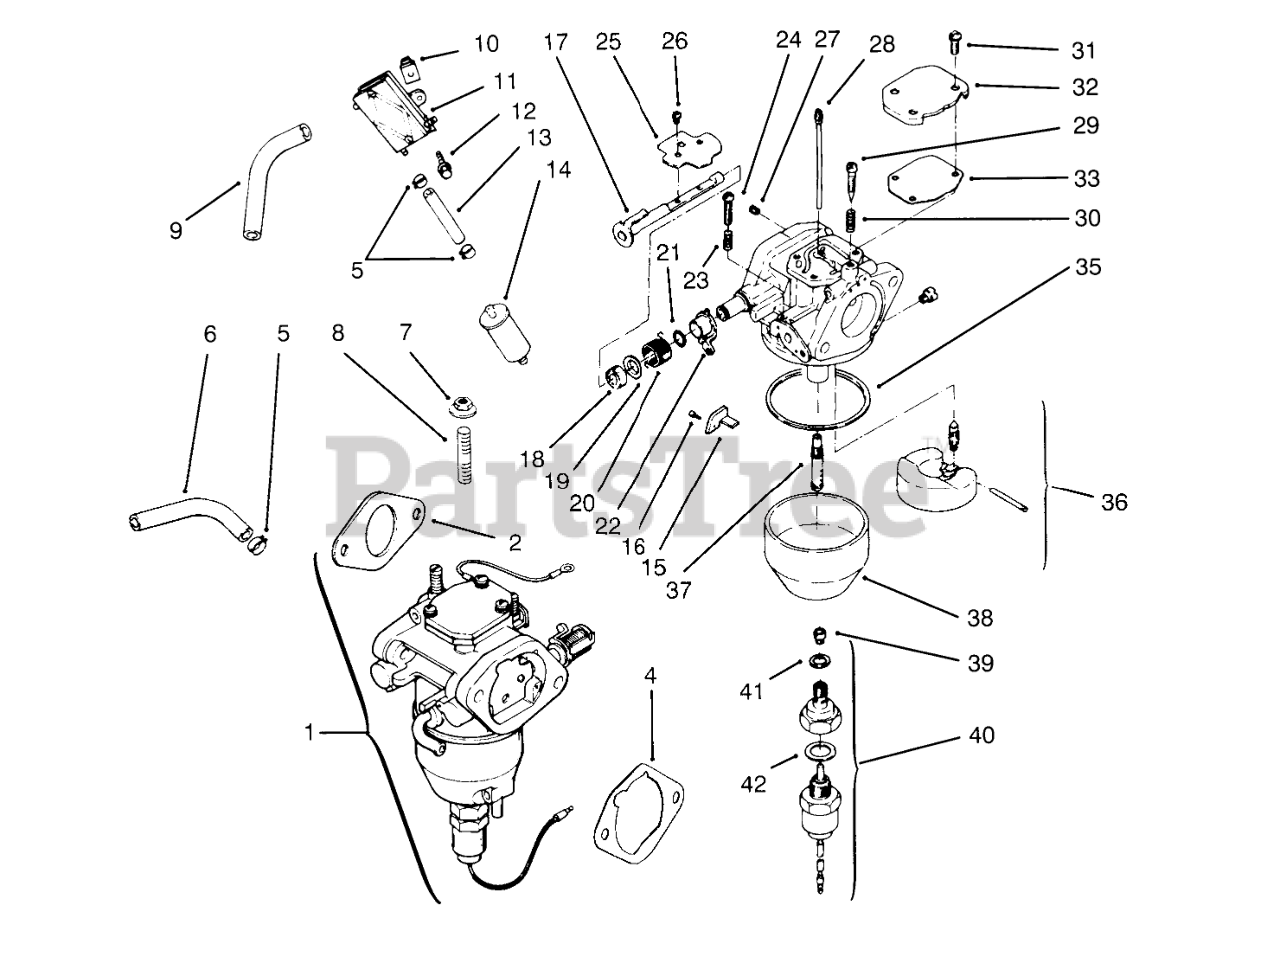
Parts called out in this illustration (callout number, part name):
1	Kit-Carb INCL 2/4/15-42 (Only On: 72103)
2	Gasket-Carburetor (Only On: 72103)
4	Gasket-A/C Base (Only On: 72103)
5	Clamp-Hose (Only On: 72103)
6	Line-Fuel 10 1 /2" (Only On: 72103)
7	Nut M6x1.0 (Only On: 72103)
8	Stud M6x1.0x95 (Only On: 72103)
9	Line-Fuel 12" (Only On: 72103)
10	Nut-Plastic (Only On: 72103)
11	Pump-Fuel (Only On: 72103)
12	Screw-Cable Clip (Only On: 72103)
13	Line-Fuel 3 1/2" (Only On: 72103)
14	Filter-Fuel (Only On: 72103)
15	Bracket-Throttle Stop (Only On: 72103)
16	Screw M2.5X45X5.5 (Only On: 72103)
17	Shaft-Choke (Only On: 72103)
18	Washer (Only On: 72103)
19	Collar-Choke (Only On: 72103)
20	Spring-Choke Return (Only On: 72103)
21	Ring-Choke Lever (Only On: 72103)
22	Lever-Choke (Only On: 72103)
23	Spring-Throttle Screw (Only On: 72103)
24	Screw-Throttle Adjust (Only On: 72103)
25	Valve-Choke (Only On: 72103)
26	Screw-Throttle Shaft (Only On: 72103)
27	Jet-Air Bleed (Only On: 72103)
28	Jet-Slow (Only On: 72103)
29	Screw-Idle Adjust (Only On: 72103)
30	Spring-Idle Adjust Screw (Only On: 72103)
31	Screw (Only On: 72103)
32	Cover-Passage (Only On: 72103)
33	Gasket-Passage Cover (Only On: 72103)
35	Gasket-Float Chamber (Only On: 72103)
36	Kit-Float Repair (Only On: 72103)
37	Nozzle-Main (Only On: 72103)
38	Chamber-Float (Only On: 72103)
39	Jet-Main (Only On: 72103)
40	Kit-Solenoid INCL 41-42 (Only On: 72103)
41	Gasket-Chamber Screw (Only On: 72103)
42	Gasket-Solenoid (Only On: 72103)
